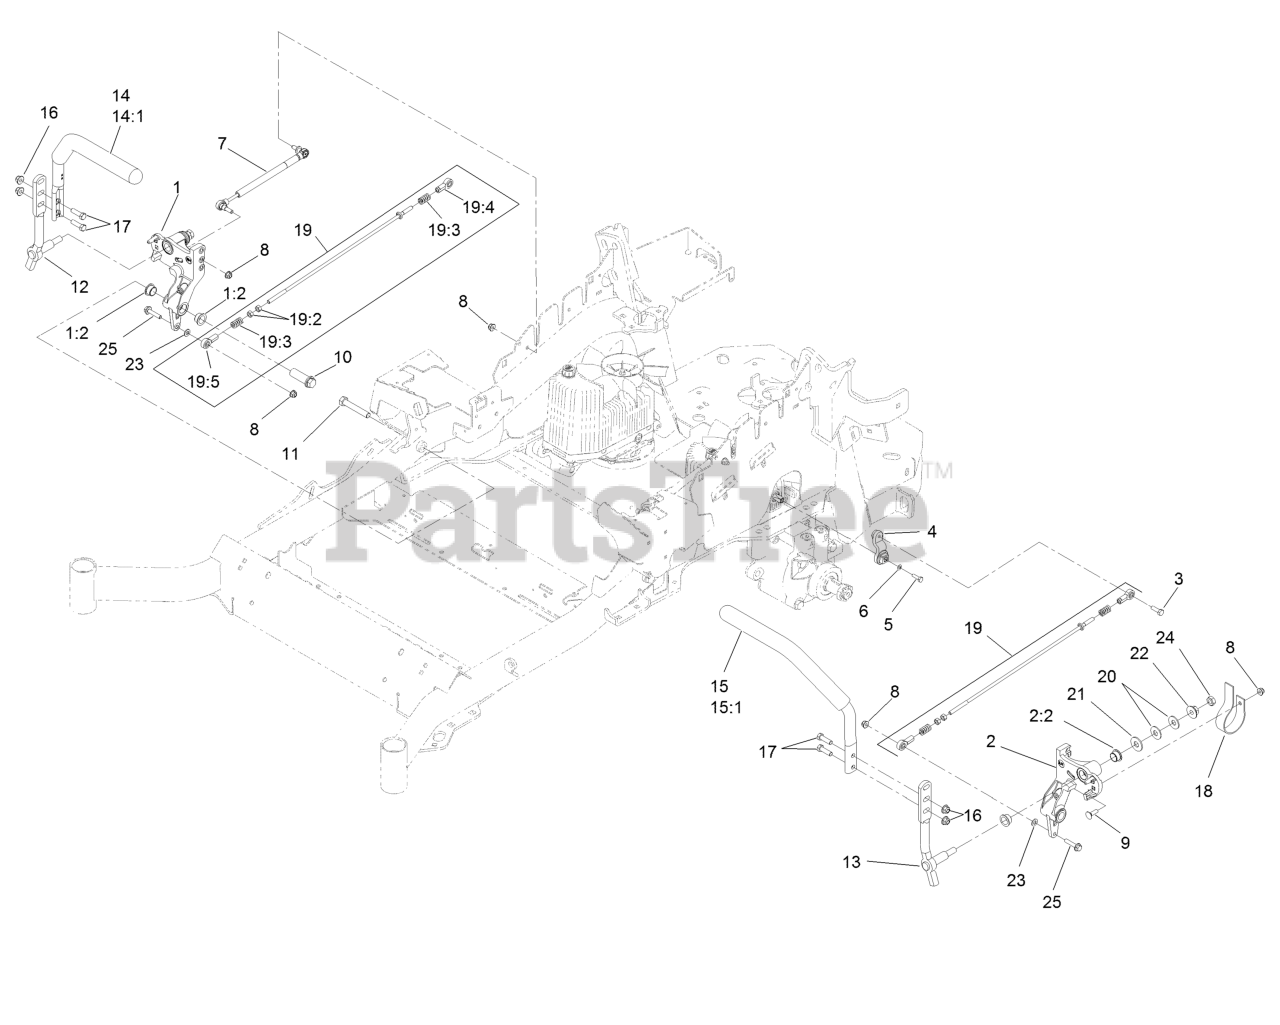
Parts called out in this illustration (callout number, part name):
1	RH Motion Control And Bushing ASM
1:2	Bushing-Flange
2	LH Motion Control And Bushing ASM
2:2	Bushing-Flange
3	Screw-HH, Thread Locking
4	Arm-Control, Pump
5	Screw-HH
6	Washer-Spring
7	Damper-Control, Motion
8	Nut-HF, NI
9	Bolt-CARR
10	Hub-Threaded
11	Screw-HH
12	Lever-Control Motion, RH
13	Lever-Control Motion, LH
14	RH Steering Handle ASM
14:1	Grip-Control, Lever
15	LH Steering Handle ASM
15:1	Grip-Control, Lever
16	Nut-HF, NI
17	Screw-HH
18	Spring-Leaf
19	Pump Linkage Rear ASM
19:2	Nut-Hex
19:3	Spring-Compression
19:4	Balljoint-LH
19:5	Balljoint-RH
20	Washer-Spring
21	Washer-Flat
23	Washer-Plain
24	Nut-Jam
25	Screw-HHF
